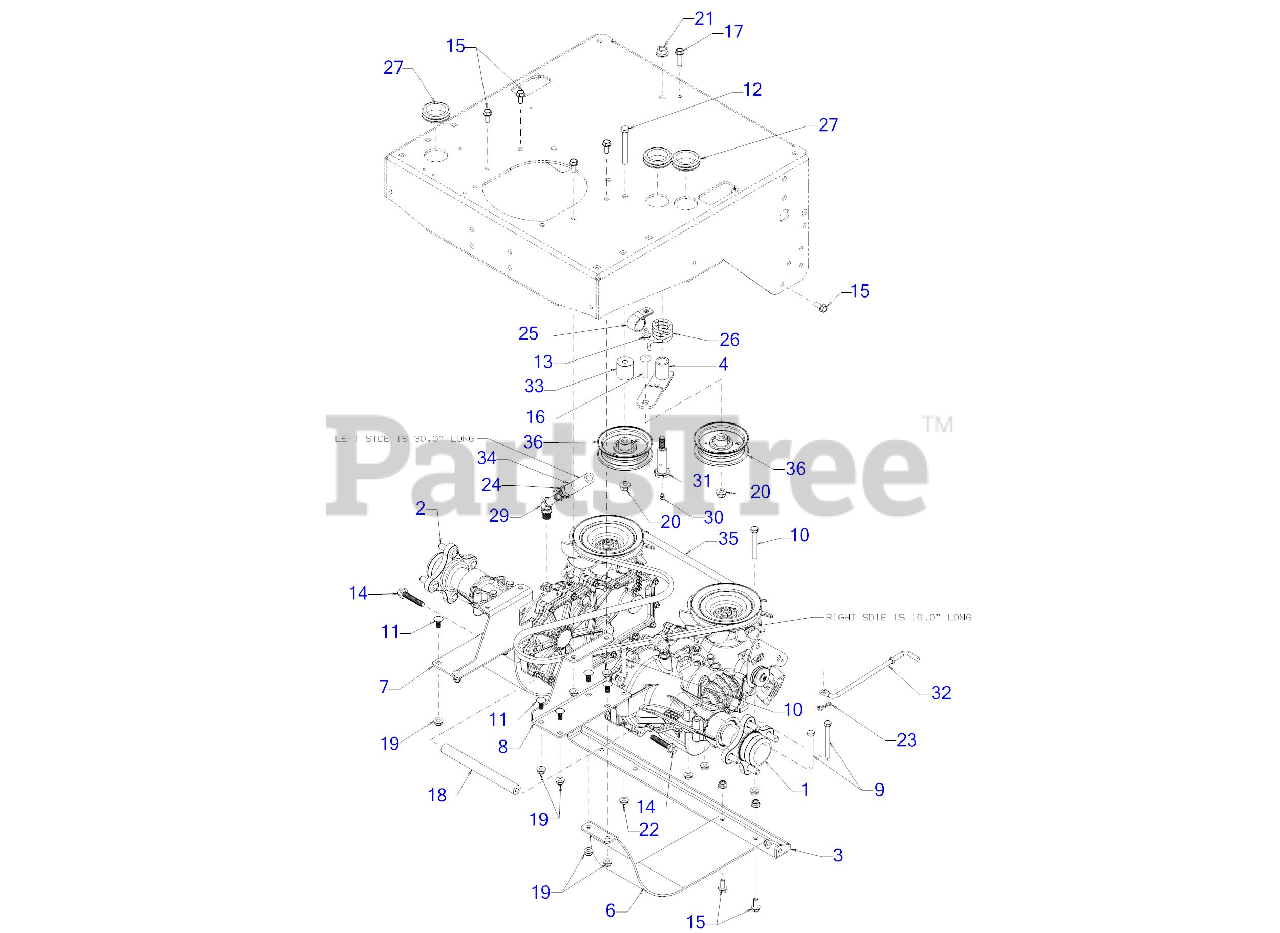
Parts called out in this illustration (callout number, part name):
1	TRANSMISSION ASSEMBLY (RH)
2	TRANSMISSION ASSEMBLY (LH)
4	IDLER ARM ASSEMBLY
9	HEX SCREW 5/16-18 x 3.00
10	SCREW 5/16-18 x 2.5 GR 5
11	CARRIAGE BOLT 5/16-18 x .75
12	SCREW 3/8-16 x 3 GR8
13	SCREW 5/16-18 x .500
14	SCREW 3/8-16 x 2.00 GR5
15	SCREW 5/16-18 x .750 GR8
16	BOLT 3/8-16 x 1.69 GR5
17	SCREW 5/16-18 x 1.25
18	SPACER (7.656 LG)
19	FLANGE LOCK NUT 5/16-18
21	FLANGE NUT 7/16-14
22	FLANGE NUT
23	BOW TIE COTTER PIN 1/4-5/16
24	FUEL HOSE CLAMP
25	HOSE CLAMP 1.0"
26	TORSION SPRING
27	RUBBER GROMMET (1.50X2.13X.563)
29	45 DEGREE FITTING (6 ORB X-8 BEAD)
30	GREASE FITTING
31	SHOULDER BOLT .68 x 2.11 7/16-14
32	BYPASS ROD
33	SPACER (0.385 X 1.25 X 1.27)
34	FUEL LINE 1/2" ID
35	V-BELT A SEC X 66.14
36	IDLER PULLEY
